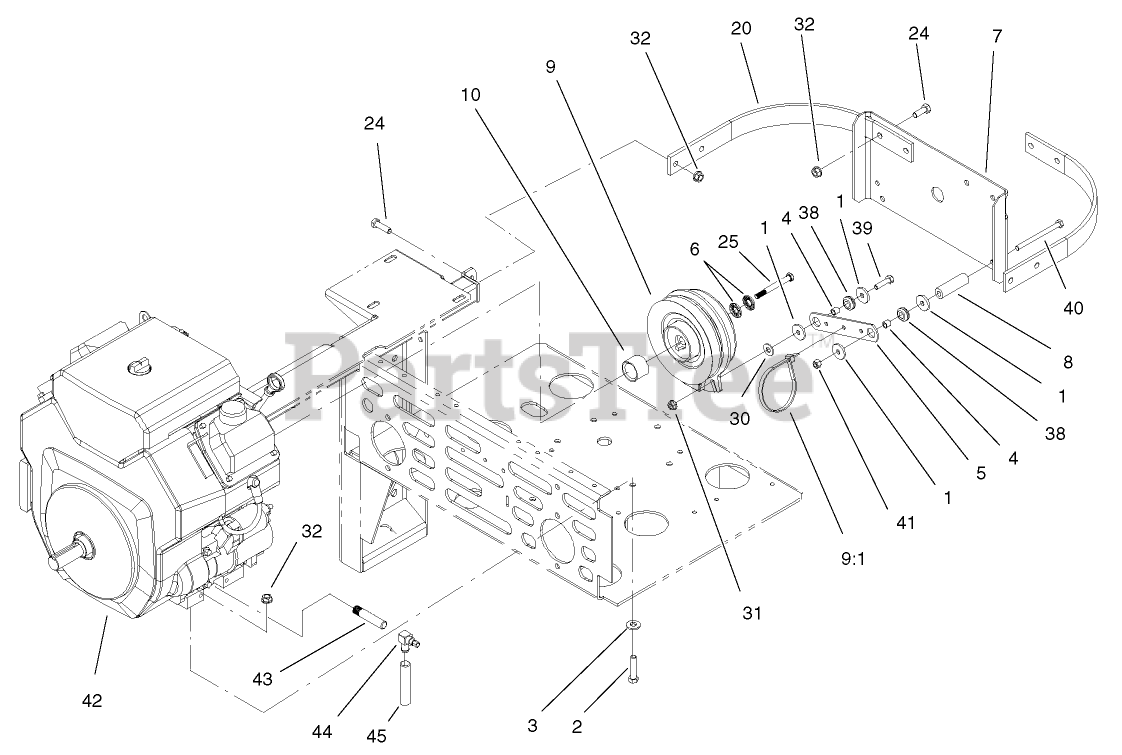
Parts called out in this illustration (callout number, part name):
1	WASHER
2	SCREW-HH
3	WASHER-BELLEVILLE
4	SPACER
5	STRAP-CLUTCH, BRAKE
6	WASHER-SPRING
7	GUARD-CLUTCH
8	SPACER-ANCHOR, CLUTCH
9	Clutch
9:1	TIE-PLASTIC
10	SPACER-CLUTCH
20	BRACKET-GUARD, TOP
24	SCREW-HH
25	SCREW-HH
30	WASHER-FLAT
31	NUT-HF
32	NUT-HHF, WHIZ
38	GROMMET
39	SCREW-HH
40	SCREW-HH
41	NUT-LOCK, NI
43	Adapter
44	Valve-Drain, Oil
45	HOSE-DRAIN, OIL
